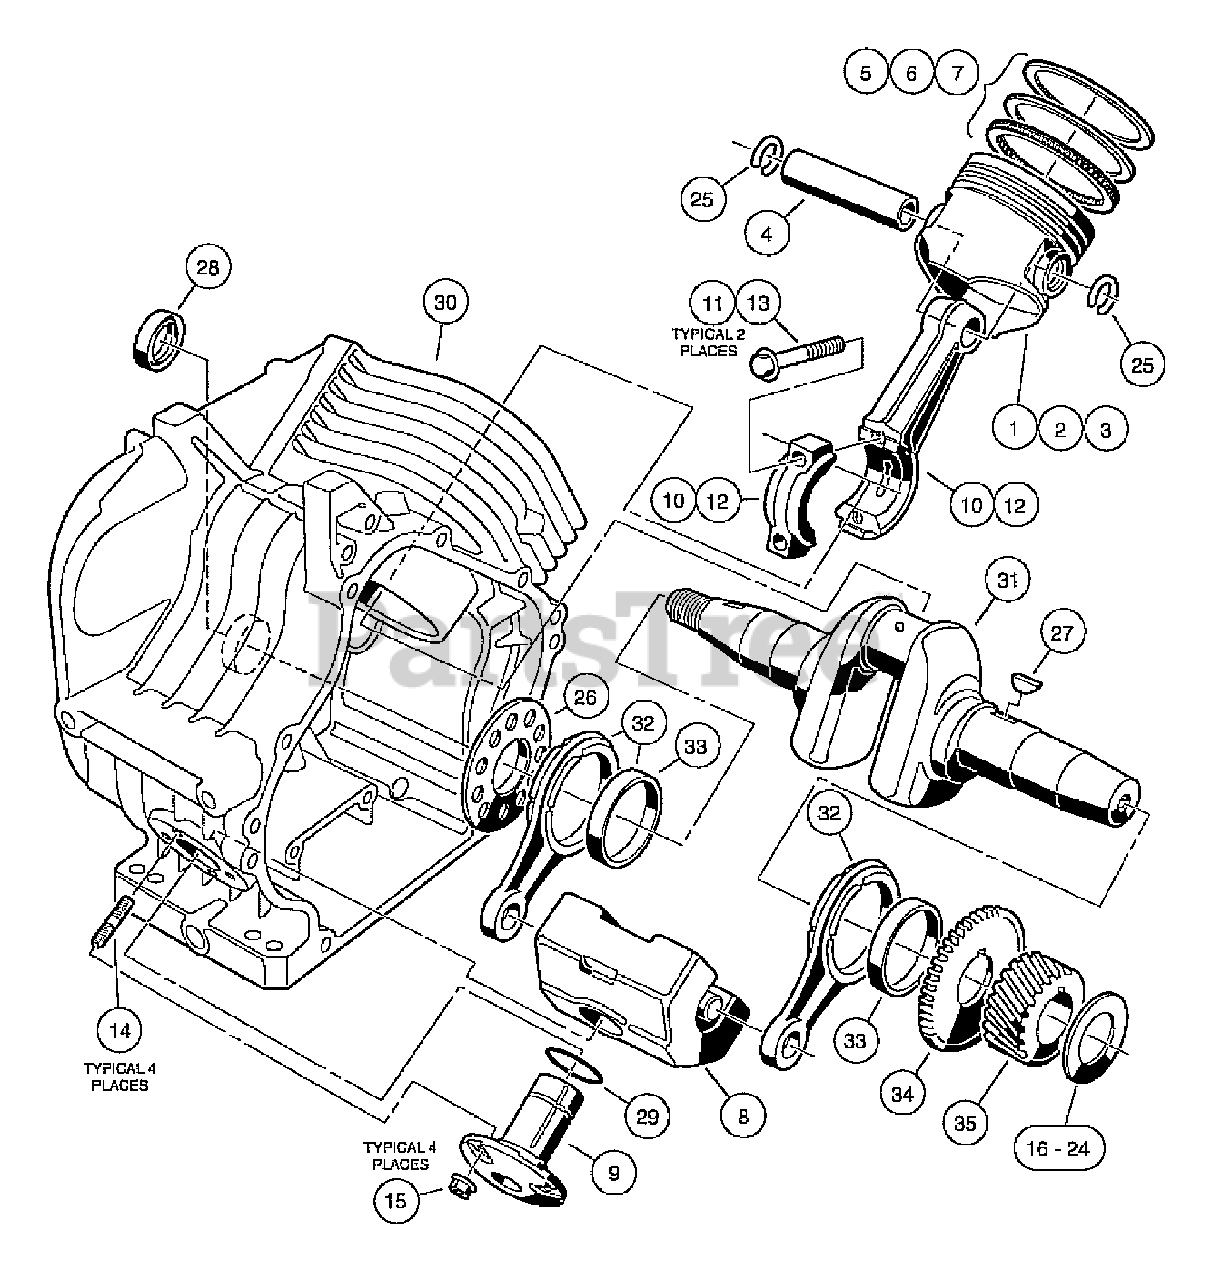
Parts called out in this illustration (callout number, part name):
1	Piston
2	Piston, Engine 0.25 mm Over
3	Piston, Engine 0.50 mm Over
4	Pin, Piston
5	Ring Set, Piston
6	Ring Set, Piston 0.25 mm Over
7	Ring Set, Piston 0.50 mm Over
8	Weight, Counterbalance
9	Shaft, Guide, Counterbalance
10	Rod Assembly
11	Bolt
12	Rod Assembly, Connecting 0.50 mm Under
13	Bolt
14	Stud, 6x14
16-24	Shim, Crankshaft T=1.13
16-24	Shim, Crankshaft T=1.18
16-24	Shim, Crankshaft T=1.23
16-24	Shim, Crankshaft T=1.28
16-24	Shim, Crankshaft T=1.33
16-24	Shim, Crankshaft T=1.3B
16-24	Shim, Crankshaft T=1.43
16-24	Shim, Crankshaft T=1.48
16-24	Shim, Crankshaft T=1.53
25	Ring, Snap
26	Spacer
28	Seal, Oil
30	Crankcase Complete, FE290 (cw)
31	Crankshaft, FE290 Left-Hand Thread
32	Rod
33	Bearing, Plane
34	Gear, Spur
35	Gear, Helical
